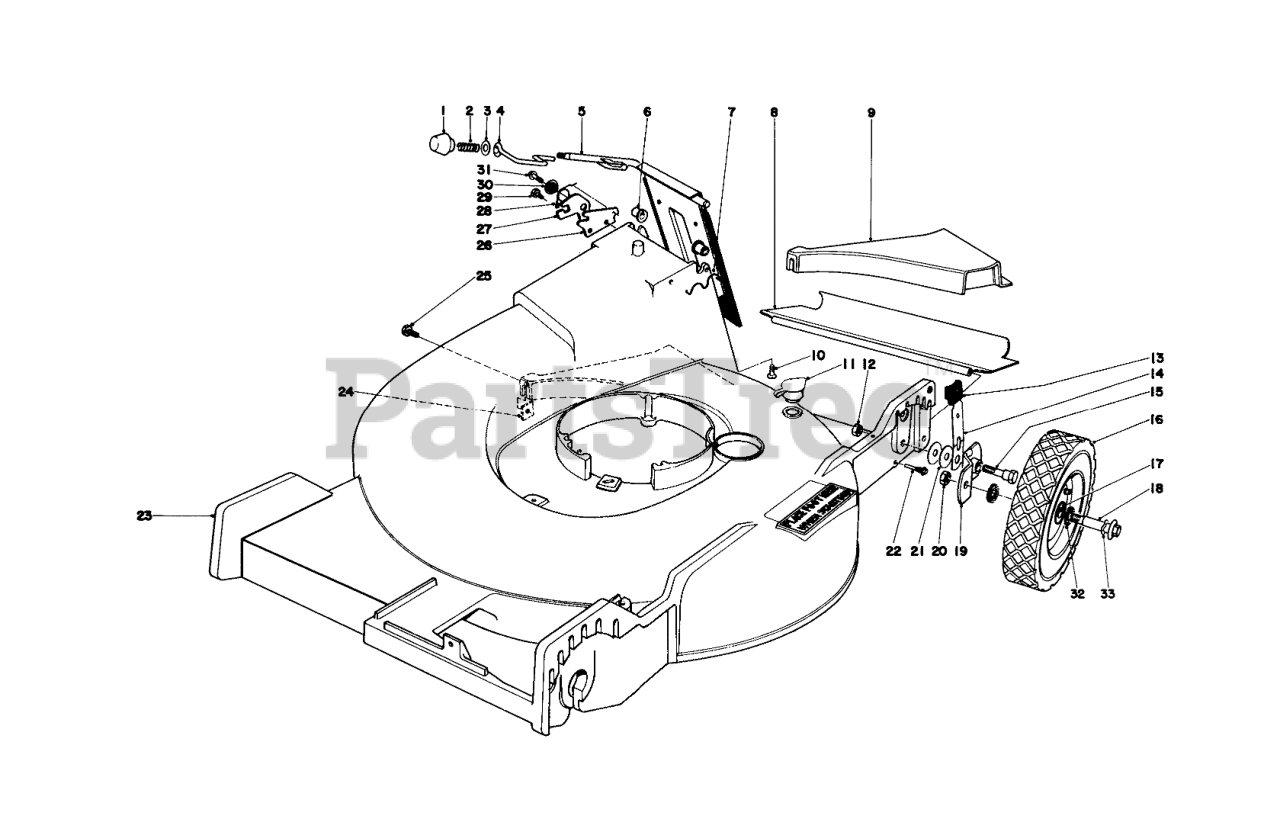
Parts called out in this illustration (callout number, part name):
2	COMPRESSION SPRING
3	WASHER
4	DOOR LATCH
5	Door Handle
6	BUSHING-NYLON
7	Door Retainer
8	REAR SAFETY SHIELD
9	REAR INSERT
10	SCREW-HH
11	WASHOUT PLUG
12	Nut
13	KNOB-ARM
14	SPRING ARM ASM
15	PIVOT SCREW
16	Wheel & Tire Assembly Rear (Incl. Ref. #17)
17	BEARING-BALL
19	PIVOT ARM ASM A
20	Nut
21	WASHER-PIVOT
22	SAFTEY SHIELD SCREW
23	Housing
24	SPECIAL NUT
25	SCREW THD 1/4 20 5/8
26	DOOR LATCH PLATE
27	Latch Safety
28	TORSION SPRING
29	SCREW-HWH
30	Latch Spacer
31	Screw
32	FELT WASHER
33	Wave Washer
